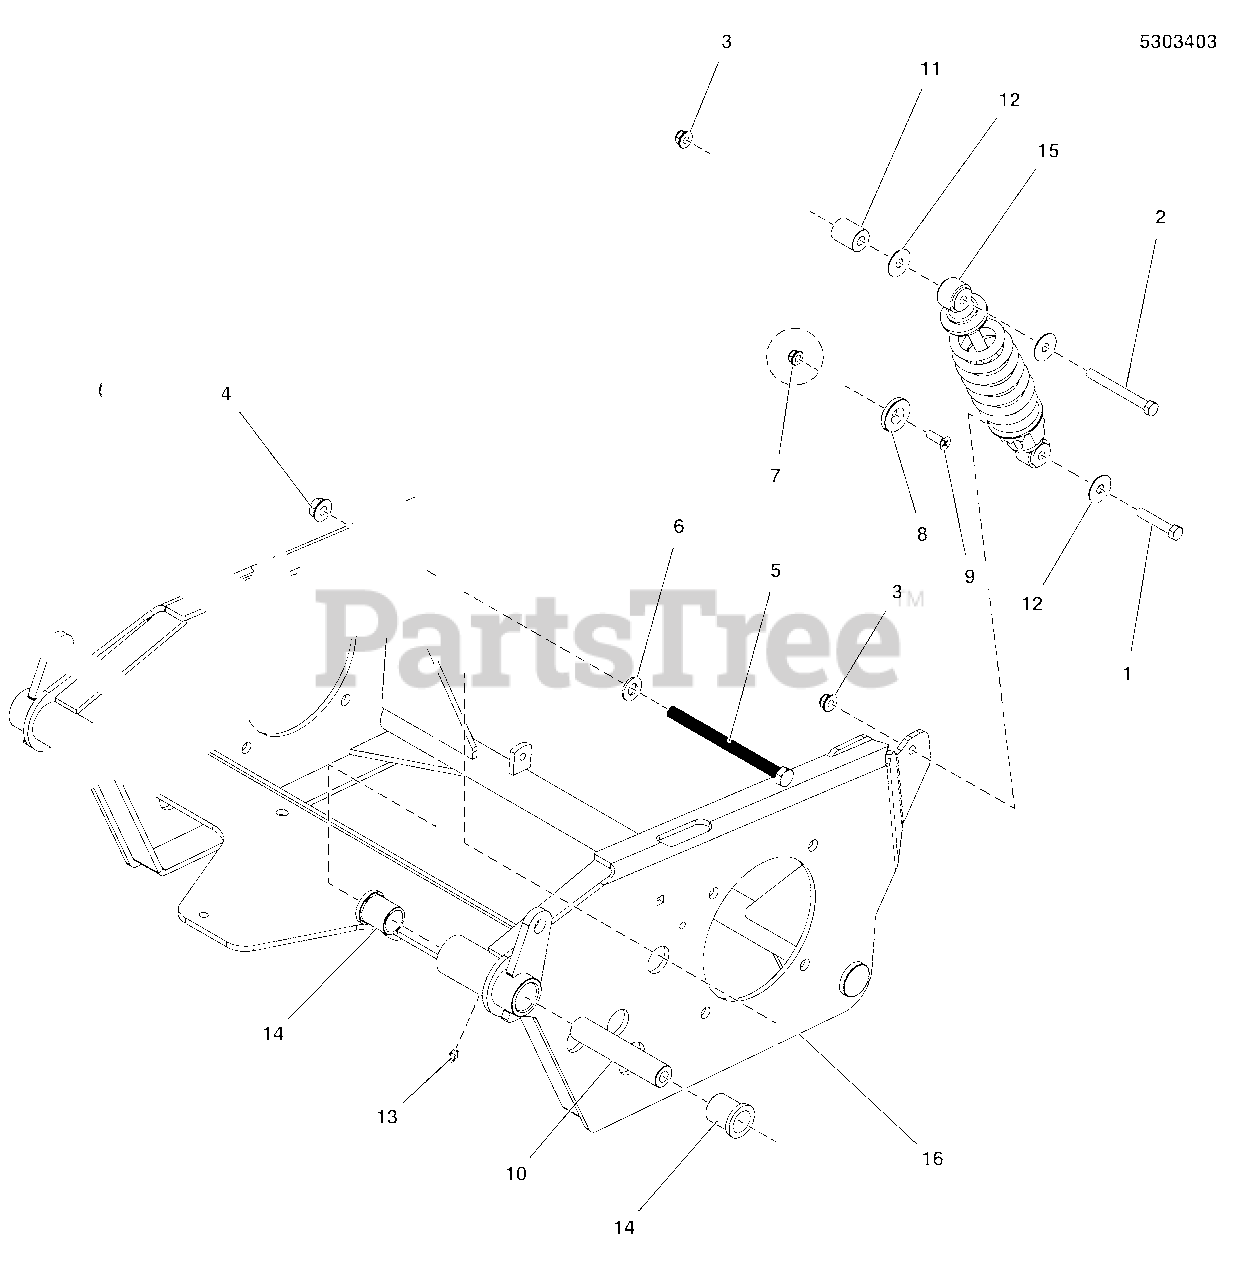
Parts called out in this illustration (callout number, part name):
1	BOLT, 3/8-16 X 2 GD5 YZ
2	BOLT, 3/8-16 X 3-1/2 GD5 CZ
3	NUT, 3/8-16 HEX NYLOCK FLANGE
4	NUT, 1/2-13 HEX NYLOCK FLANGE
5	BOLT, 1/2-13 X 6-1/2 GD8, YZ
6	WASHER, 1/2 SAE
7	NUT, 5/16-18 HEX NYLOCK FLANGE
8	SPACER, .34 X 1.54 X .25, PL
9	SCREW, 5/16-18X1, PHILLIPS HD. BZ
10	SPACER, .52 X 1.00 X 5.00
11	SPACER, .39 X 1.00 X 1.25, CZ
12	WASHER-3/8 FENDER
13	GREASE FITTING, 1/4-28 STRAIGHT
14	BUSHING, FLANGE
15	SHOCK / SPRING ASSEMBLY, OE22376
16	WELD, TRANSMISSION CARRIAGE, IS2100 - ORG
